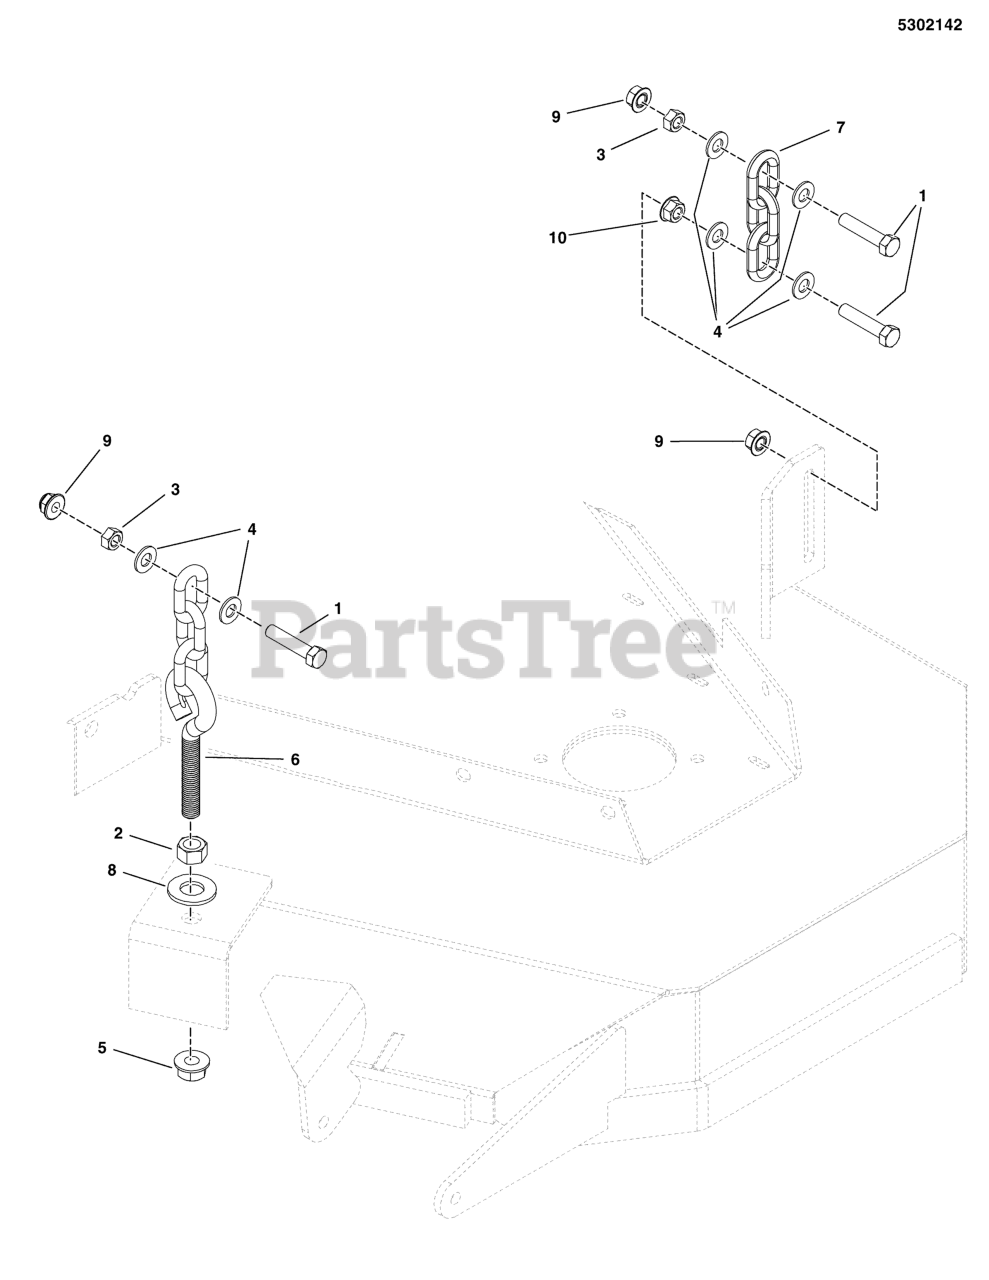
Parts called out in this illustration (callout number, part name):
1	BOLT, 3/8-16 X 1-3/4" GD5 CZ
2	NUT, 1/2-13 HEX, YZ
3	NUT, 3/8-16 HEX JAM
4	WASHER, 3/8 SAE
5	NUT, Hex Flange, Nylock, 1/2-13
6	HANGER, FRONT DECK-3LINK, 5.5" EB
7	CHAIN, 5/16 GD30, 3 LINKS
8	WASHER, 1/2 SAE
9	NUT, 3/8-16 HEX NYLOCK FLANGE
10	NUT, 3/8-16 HEX SERRATED FLANGE
